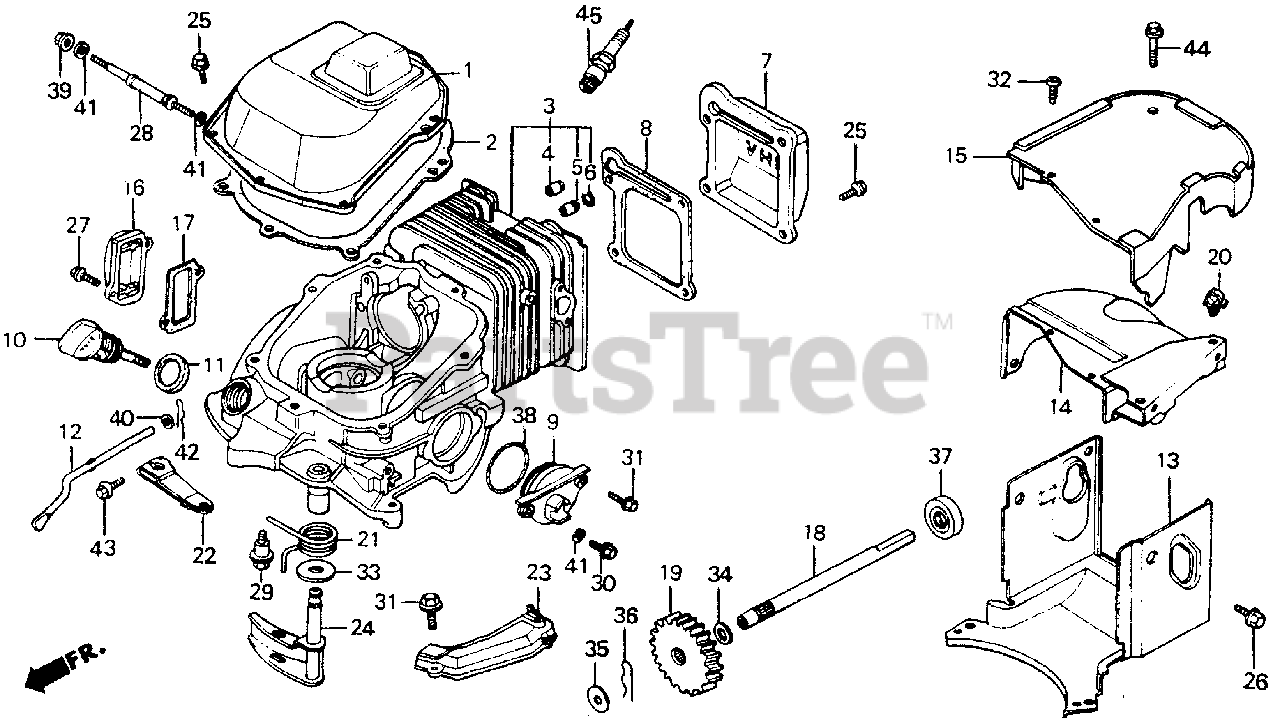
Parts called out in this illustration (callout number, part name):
1	COVER, CRANKCASE (NOT AVAILABLE)
2	GASKET, CRANKCASE COVER
3	CYLINDER
4	GUIDE, VALVE (OVER SIZE)
5	GUIDE, EX. VALVE (OVER SIZE)
6	CLIP, VALVE GUIDE
7	COVER, HEAD (NOT AVAILABLE)
8	GASKET, CYLINDER HEAD COVER (NOT AVAILABLE)
9	COVER, CAMSHAFT
10	CAP, OIL FILLER (NOT AVAILABLE)
11	GASKET, OIL FILLER CAP
12	SHAFT, GOVERNOR ARM
14	COVER, AIR IN.
15	GRID, AIR IN. SCREEN
16	COVER, REDUCTION
17	GASKET, REDUCTION COVER (NOT AVAILABLE)
18	SHAFT, P.T.O. (NOT AVAILABLE)
19	GEAR, P.T.O. DRIVE
20	CLIP, IGNITION WIRE (8MM)
21	SPRING, BRAKE
22	LEVER, BRAKE
23	COVER, BRAKE
24	BRAKE (NOT AVAILABLE)
25	BOLT, FLANGE (6X12)
26	BOLT, FLANGE (6X12) (CT200)
27	BOLT, FLANGE (6X14) (CT200)
28	BOLT, SPECIAL (6MM)
29	BOLT, SPECIAL (6MM)
30	BOLT, FLANGE (6X20) (CT200)
31	BOLT, FLANGE (6X16) (CT200)
32	SCREW, TAPPING (4X8)
33	WASHER, BRAKE ARM (NOT AVAILABLE)
34	WASHER (10X24)
35	WASHER, THRUST (12MM)
36	PIN, LOCK (2.0)
37	OIL SEAL (12X22X5)
38	O-RING (47.7X2.5) (ARAI)
39	NUT, FLANGE (6MM)
40	WASHER, PLAIN (6MM)
41	WASHER, PLAIN (6MM)
42	PIN, LOCK (6MM)
43	BOLT, FLANGE (6X22)
44	BOLT, FLANGE (6X18)
45	SPARK PLUG (BR-4HS) (NGK)
